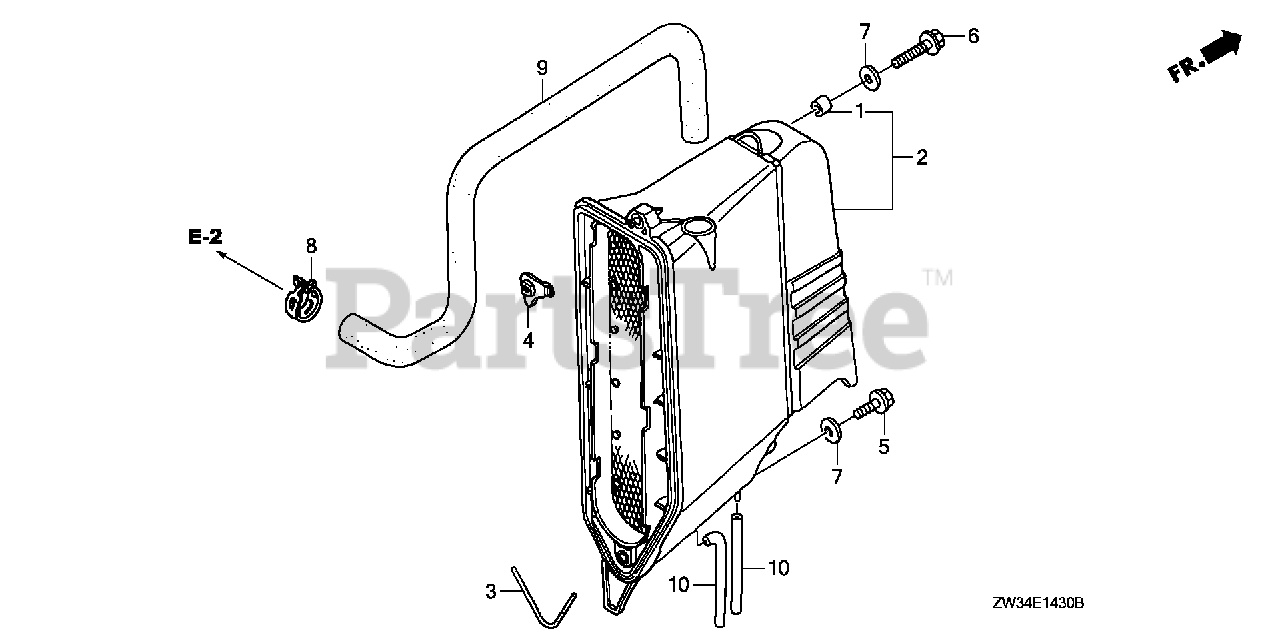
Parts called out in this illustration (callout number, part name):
1	COLLAR, DISTANCE
2	COVER, MUFFLER
3	GASKET, MUFFLER COVER
4	NUT, MUFFLER COVER
5	BOLT, FLANGE (6X25)
6	BOLT, FLANGE (6X40)
7	WASHER (6.5X18)
8	CLAMP, TUBE (D17)
9	TUBE, BREATHER
10	BULK HOSE, VINYL (4.5X8X1000) (4.5X8X750)
